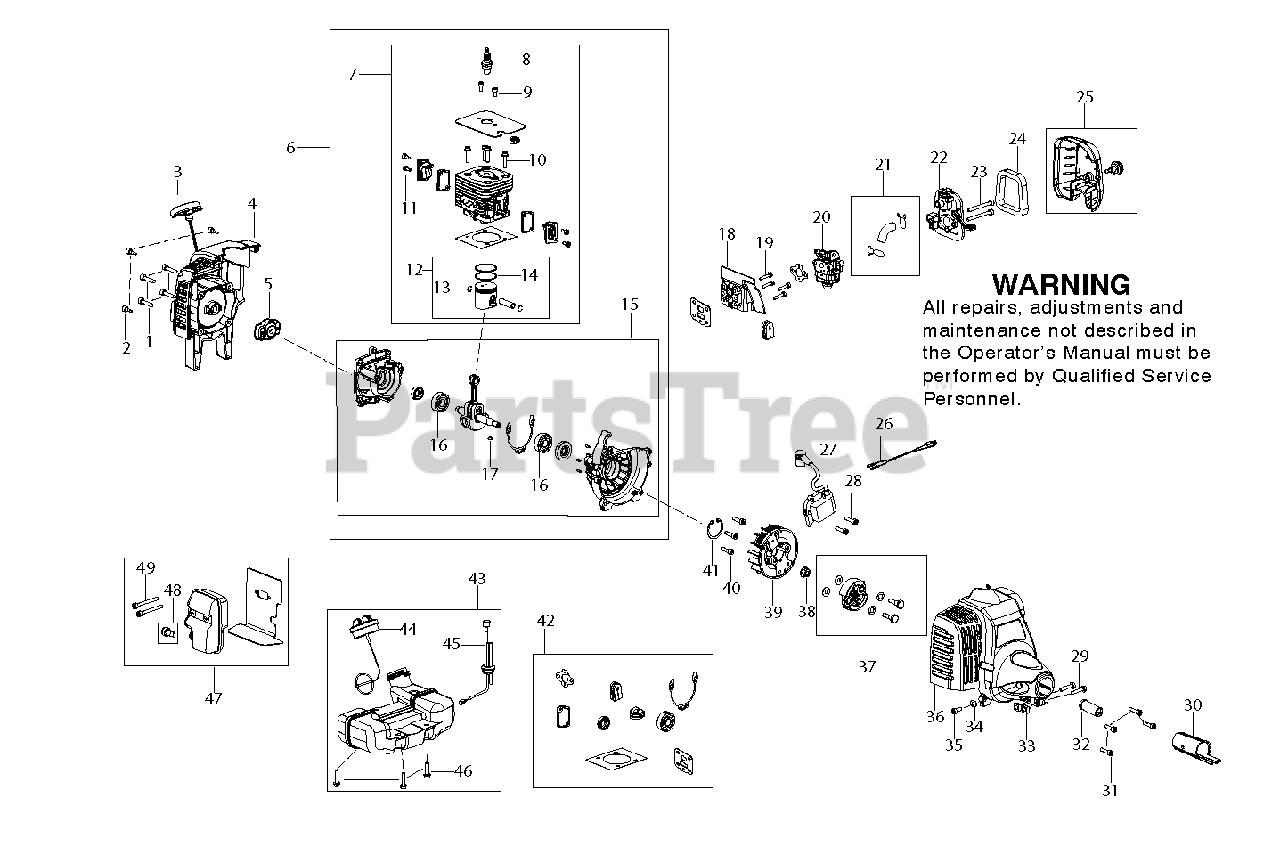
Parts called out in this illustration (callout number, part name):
1	SCREW KIT 4 PACK
3	ROPE & HANDLE KIT
4	KIT
5	PAWL ASSY
6	SHORT BLOCK KIT ASSY LT30
7	CYLINDER & PISTON KIT
8	Spark Plug, RZ7C
9	SCREW (4-PACK)
10	SCREW (4-PACK)
11	SCREW 4 PACK
12	PISTON RING KIT
14	PISTON RING
15	C'CASE & C'SHAFT KIT
16	BEARING (2-PACK)
17	KEY 6221-830301
19	SCREW (4-PACK)
20	CARBURETOR
21	INTAKE TUBE KIT
22	AIR BOX BASE ASSY
25	AIR BOX COVER ASSY
26	COIL WIRE
27	IGNITION MODULE
36	FAN HSG ASSY KIT
37	CLUTCH ASSY
39	FLYWHEEL
42	GASKET KIT
43	FUEL TANK ASSY
44	ASSEMBLY
45	KIT FUEL LINE ASSEMBLY
47	MUFFLER ASSY
48	KIT
49	SCREW (2-PACK)
